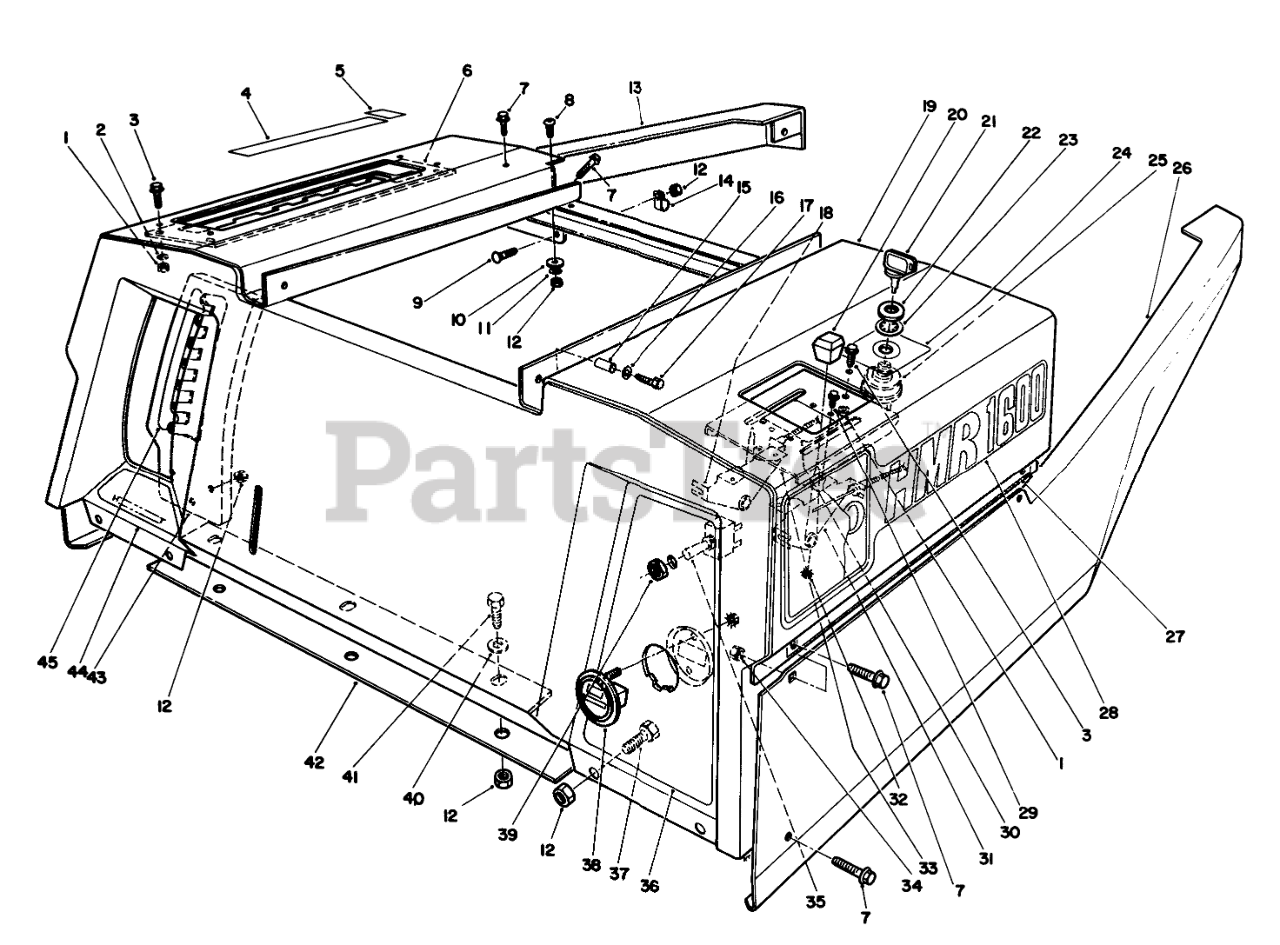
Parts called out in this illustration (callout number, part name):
1	NUT-LOCK, NI
2	WASHER-FLAT
3	SCREW-HHF
4	DECAL - SHIFT
5	DECAL - REVERSE
6	GATE-SHIFT B
7	SCREW-HHF
8	SCREW-HSBH
9	BOLT-CARR
10	RUBBER WASHER
11	WASHER-FLAT
12	NUT-LOCK, NI
13	RH FENDER WA R
14	CLAMP-R
15	SPACER
16	WASHER-FLAT
17	SCREW-HH
18	CHOKE CONTROL
19	Body (Incl. Ref. #8, 10, 11, 12, 24, 27, 28, 36, 44)
21	KEY-IGNITION
22	NUT-HH
23	WASHER-TOOTH, INTERNAL
24	DECAL - IGNITION
25	Switch-Starter (Incl. Ref. #22 & 23)
26	LH FENDER WA R
27	DECAL - STEERING (L)
28	DECAL - 1600
29	SCREW-HWH
30	DECAL - THROTTLE
31	THROTTLE CONTROL
32	NUT-KEPS
33	CONTROL PLATE B
35	Switch (Incl. Ref. #39)
36	DECAL - DECK SWITCH
37	SCREW-HH
38	GAUGE-HOURMETER
39	NUT
40	WASHER-PLAIN
41	SCREW-HH
42	FLOOR PAN GASKET
43	HOC QUADRANT B
44	DECAL - HEIGHT OF CUT
45	DECAL - HOC
